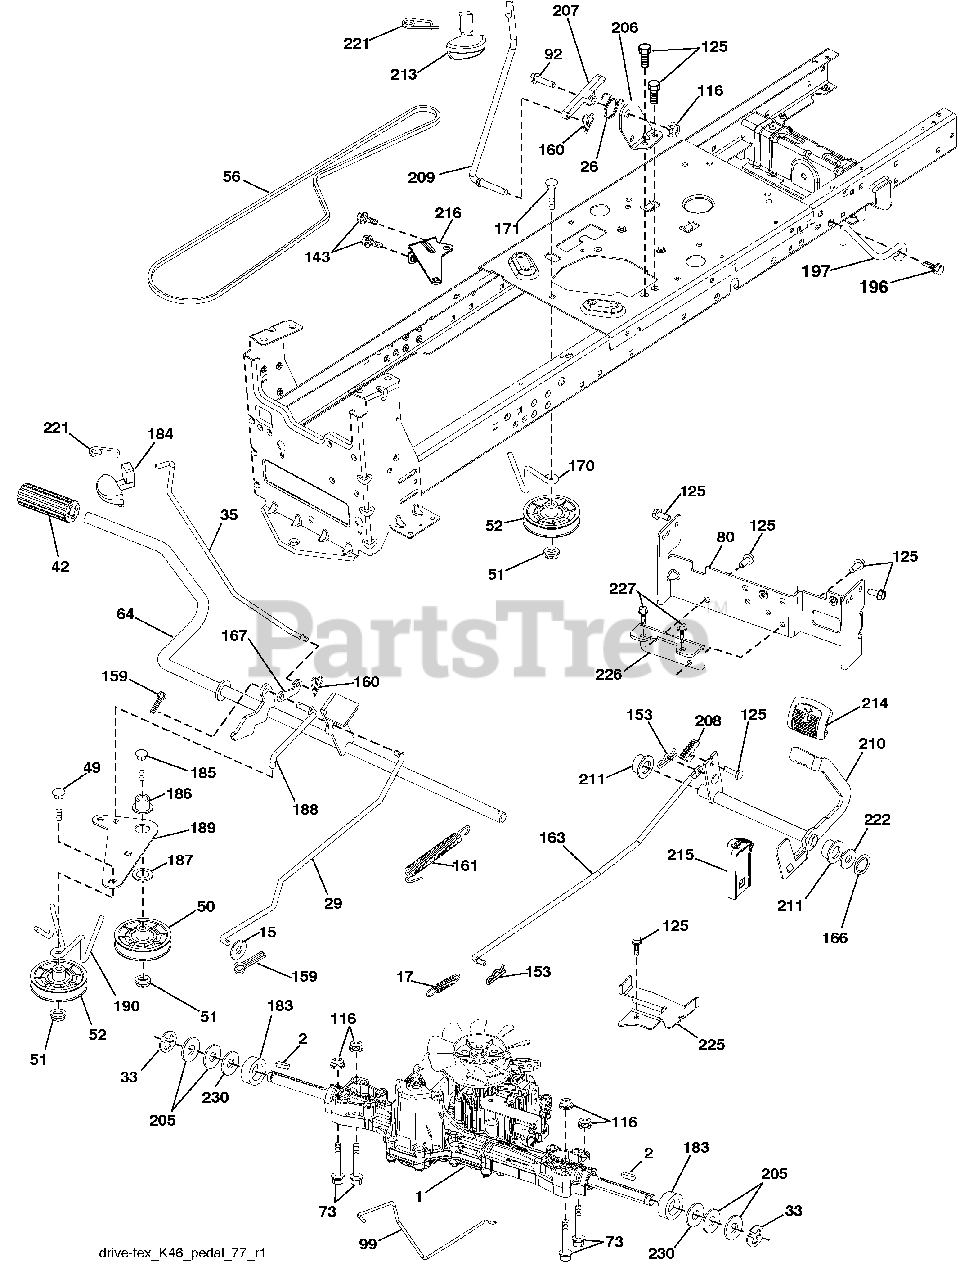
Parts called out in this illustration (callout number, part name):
1	Transaxle, TUFFTORQ K46 BT (See Transaxle breakdown)
15	Washer 13/32 x 13/16 x 16 Ga.
17	Spring, Brake
26	Spring Return Cruise
29	Rod, Brake
35	Rod, Brake, Park
42	Cover, Foot Pedal
50	Pulley Idler Flat
51	Lock Nut 3/8-16
52	Idler V-Groove 910" Offset
56	V-Belt, Drive
64	Shaft Asm. Pedal Brake Control
73	Bolt Hex Flghd 5/16-18 Gr. 5
80	Bracket Strap Torque
92	Bolt Fin Hex 5/16-18 unc x 1.25
99	Rod Spring Bypass
116	Nut Lock Hex Flange 5/16-18
125	Screw 5/16-18 x 3/4
143	Screw 5/16-18 x 1/2
153	Retainer Spring
159	Pin Cotter 1/8 x 3/4
160	Retainer Clip
161	Spring, Return, Clutch
163	Rod Pedal Control
167	Latch Brake Parking
170	Keeper Belt Centerspan
171	Bolt RDHD SQNK 3/8-16 unc x 2
183	Spacer Split
184	Handle Parking Brake
185	Bolt Rdhd 3/8-16 unc x 2-3/4 Gr. 5
186	Spacer Retainer
187	Washer
188	Link Clutch Ground Drive
189	Bellcrank Ground Drive
190	Keeper Bellcrank Ground Drive
196	Screw 3/8-16 x 1
197	Bracket Clutch Anti-Rotation
206	Bracket Mount Latch Cruise
207	Latch Control Cruise
208	Gear Sector Control Cruise
209	Rod Control Cruise
210	Rocker Asm. Pedal Control
211	Bearing Nylon
213	Knob Control Cruise
214	Pedal Forward
215	Pedal Reverse
216	Bracket Pulley Idler
221	Retainer Spring Clip Handle
222	Washer 21/32 x 1-1/4 10 Ga.
225	Keeper Belt Trans.
226	Bracket Mount Torque
227	Screw Thdrol 5/16-18 x 3/4
230	Washer Hardened
